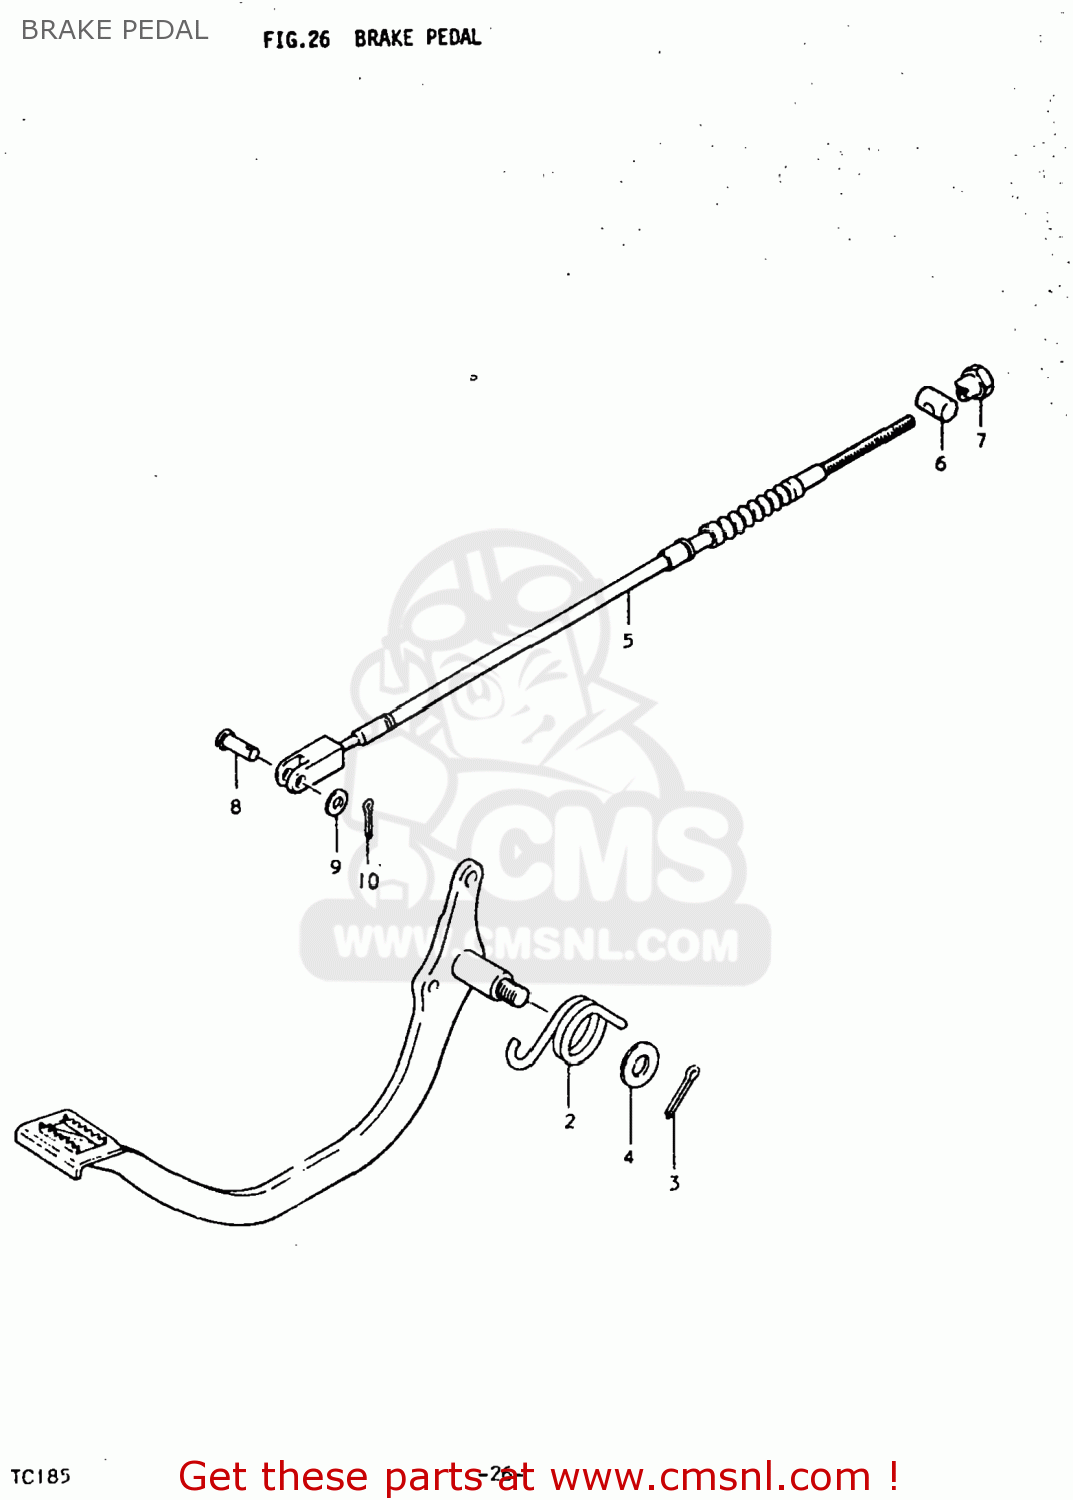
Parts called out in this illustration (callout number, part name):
1	PEDAL,BRAKE
2	SPRING
3	COTTER PIN
4	WASHER(15.5X26X2.3)
5	CABLE,RR BRAKE
6	PIN(11X18)
7	NUT
8	PIN(L:17.5)
9	WASHER
10	PIN
